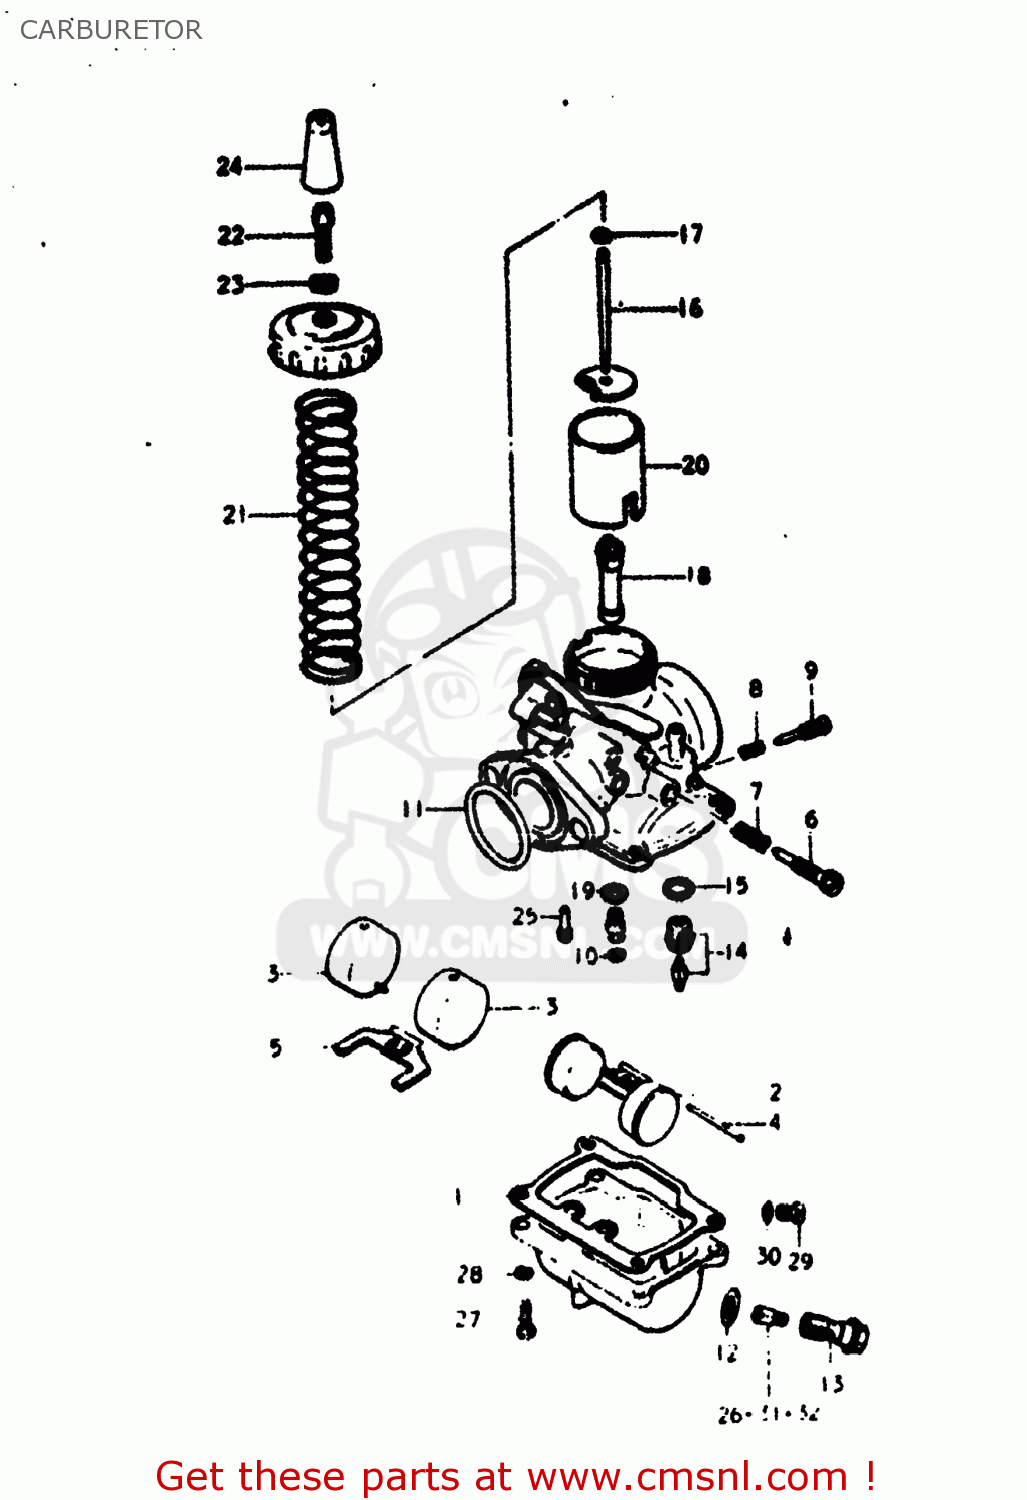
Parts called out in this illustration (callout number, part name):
0	CARBURETOR ASSEMBLY
1	GASKET,FLOAT CHAMBER (NAS)
2	FLOAT
3	FLOAT
4	PIN,FLOAT
5	ARM,FLOAT
6	SCREW
7	SPRING,THROTTLE SCREW
8	SPRING
9	SCREW,PILOT AIR
10	O RING
11	O RING
12	WASHER
13	HOLDER
14	VALVE ASSY,NEEDLE
15	GASKET,VALVE SEAT (NAS)
16	NEEDLE JET
17	CLIP
18	JET,NEEDLE
19	WASHER
20	VALVE,THROTTLE
21	SPRING, THROTTLE VALVE
22	ADJUSTER,CABLE
23	NUT
24	CAP,CABLE ADJUSTER
25	JET
26	JET
27	SCREW
28	LOCK WASHER
29	PLUG
30	GASKET,DRAIN,PLUG (NAS)
31	JET
32	JET
